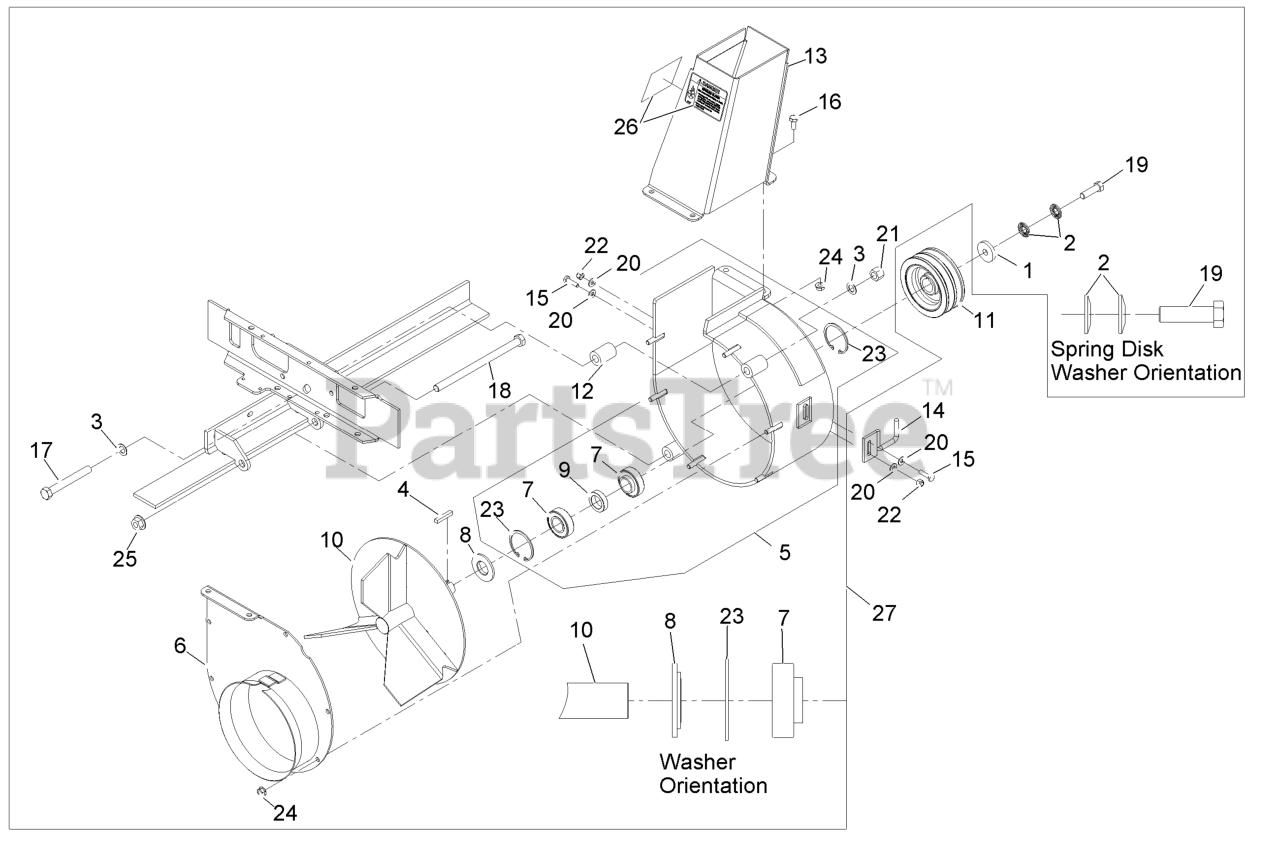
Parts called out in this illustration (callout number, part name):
1	WASHER-CLUTCH
2	WASHER-SPRING
3	WASHER-THRUST
4	KEY-SQUARE
5	ASM,HOUSING W/BEARINGS
6	COVER-BLOWER
7	BEARING-BALL
8	SPACER-BLOWER
9	SPACER-BEARING
10	IMPELLER-3 BLADE
12	SPACER-MOUNT
13	DISCHARGE CHUTE ASM
15	SCREW-HH
16	SCREW-HH
17	SCREW-HH
18	SCREW-HH
19	SCREW-HH
20	WASHER-FLAT
21	NUT-LOCK, NI
22	NUT-LOCK, NI
23	RING-SNAP
25	NUT-HHF
26	DECAL-DANGER IMPELLER
27	ASM,BLOWER COMPLETE
